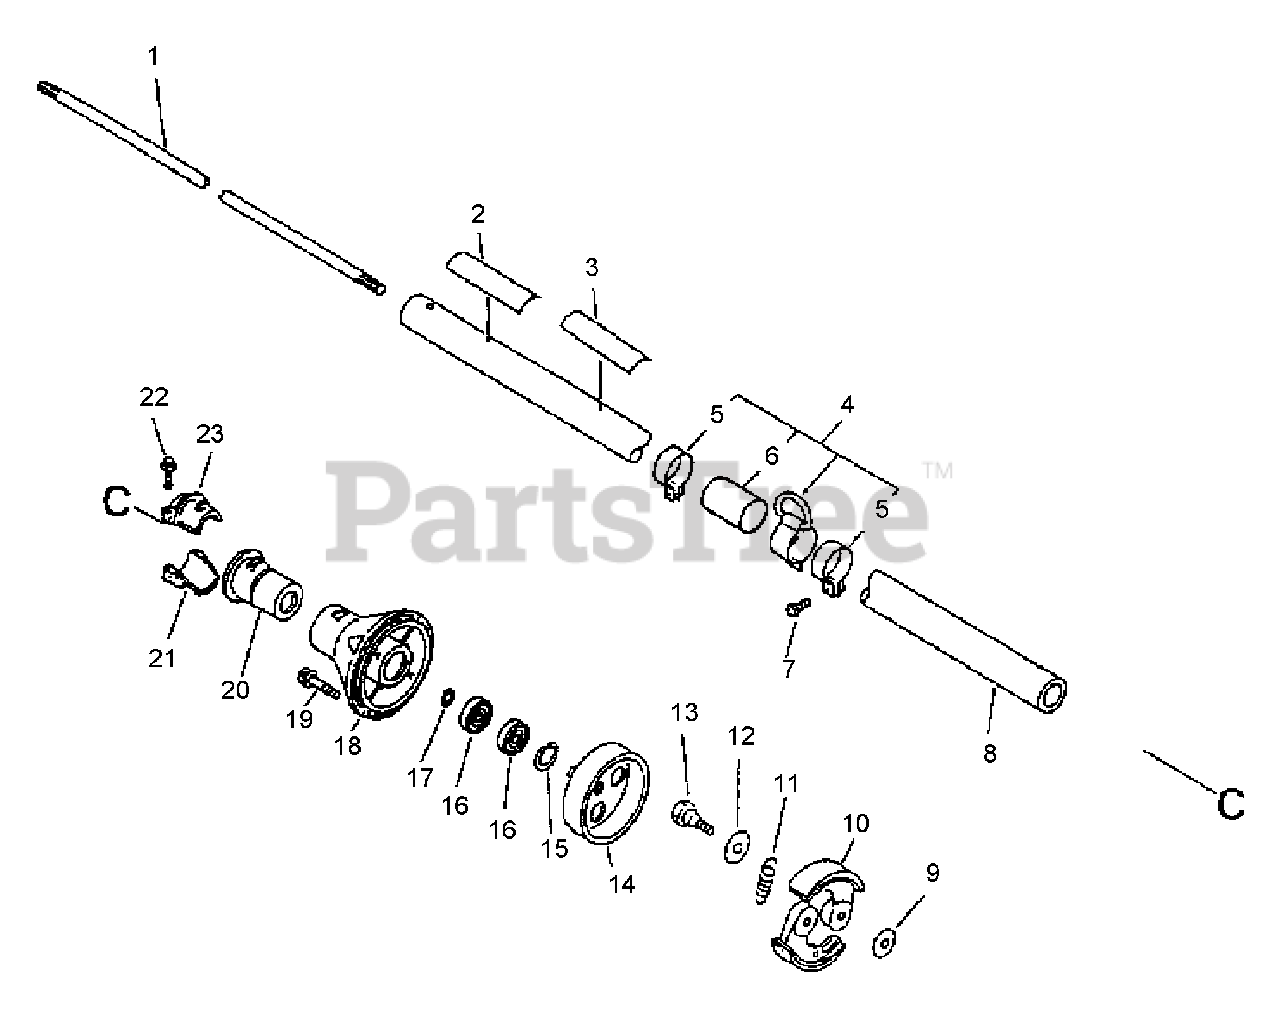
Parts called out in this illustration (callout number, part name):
1	DRIVESHAFT
2	LABEL, CAUTION
3	LABEL, CAUTION
4	HANGER ASSY
5	CLAMP
6	COLLAR
7	SCREW 5×14
8	MAIN PIPE ASSY 25×1500
9	WASHER 8.2×17×1.6
10	SHOE, CLUTCH
11	SPRING, CLUTCH
12	WASHER 10.2×18×1.0
13	BOLT, CLUTCH
14	DRUM, CLUTCH
15	RING, SNAP 28
16	BEARING, BALL 6001
17	RING, RETAINING - 12
18	CASE, CLUTCH
18	CASE, CLUTCH DRUM
19	BOLT 5×20
20	CUSHION
21	HOLDER
21	HOLDER, MAIN PIPE
22	BOLT - 5×25
23	CLAMP, MAIN PIPE
